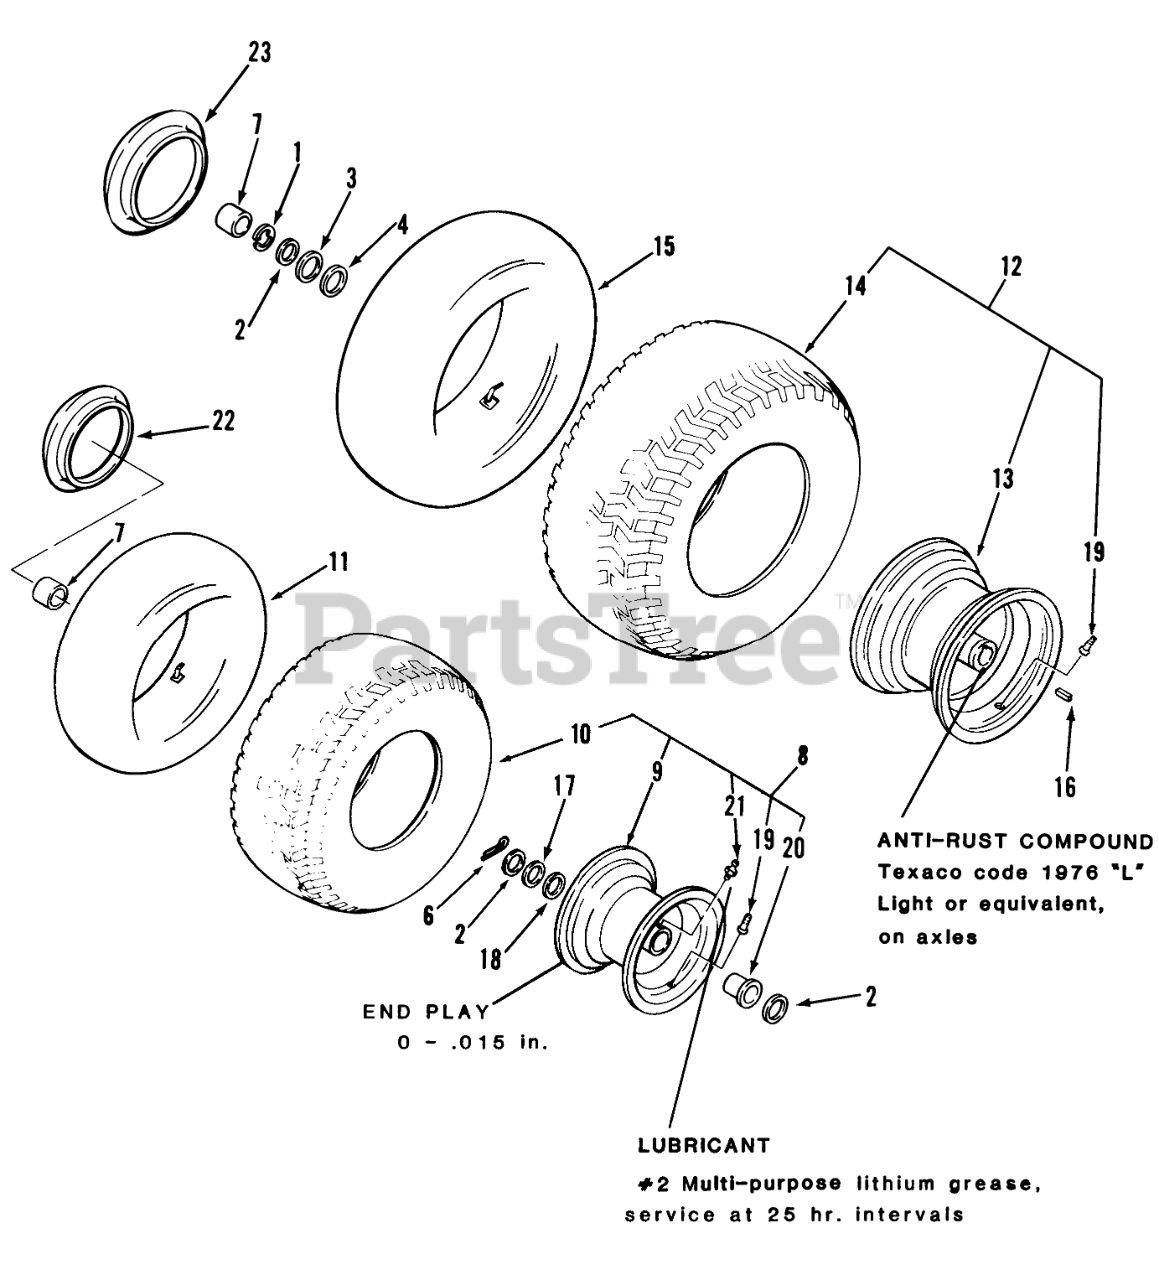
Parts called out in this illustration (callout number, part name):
1	E RING
2	WASHER-WHEEL
3	WASHER-SHIM
3	Washer
4	WASHER
6	COTTER PIN-4
7	HUB CAP-FLAT BLACK
8	Assy-Wheel & Tire Front
9	Front Wheel (includes Rims items 19, 20 & 21)
10	TIRE15 X 6.00-6
12	Assy-Wheel & Tire-Rear 252-H
12	Assy-Wheel & Tire-Rear 257-H
13	Rear Wheel (Complete)
14	TIRE 22 X 7.50-12
14	TIRE 22 X 9.00-12
15	INNER TUBE
15	TUBE-INNER
16	Key
17	WASHER
18	WASHER-SHIM
19	VALVE
20	BEARING-WHEEL
21	ZERK-GREASE
22	6"-HUB CAP LOGO
23	12"-HUB CAP LOGO
